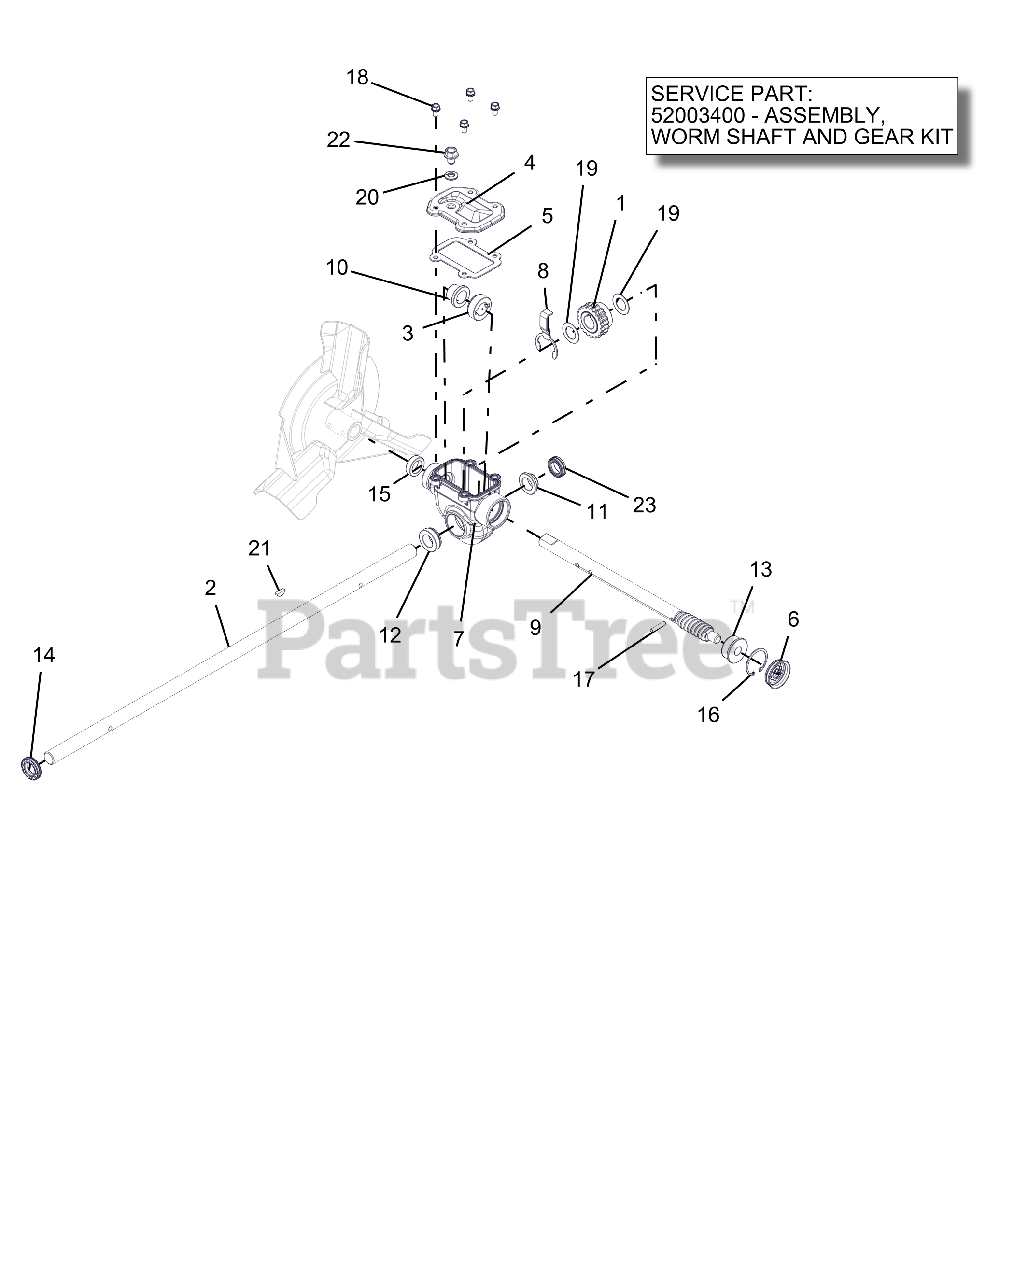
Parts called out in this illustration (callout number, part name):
1	WORM GEAR
2	SHAFT, RAKE-28" (.750 DIA)
3	THRUST COLLAR, .75" ID SLIPFIT
4	COVER, TOP - COMPACT
5	GASKET, TOP - COMPACT GEARCASE
6	COVER, GEAR CASE 1.50"
7	GEARCASE, COMPACT ALUMINUM
8	BUSHING RETAINER, COMPACT
9	SHAFT, WORM - COMPACT
10	BSHG-FLG .755X.878X.75X1.25
11	BSHG-FLG .755X.878X.424X1.25
12	BSHG-FLG COMPACT, RIGHT
13	BSHG-FLG .503X1.303X.62X1.465
14	SEAL-OIL .748X1.300X.250 TBC29
15	SEAL-OIL .748X1.125X.312 TB2-H
16	RG-RTNG-INT 1.500X.050
17	PIN-STR .188X1.00 6150
18	BOLT, SEMS .25-20X.50 GR5 YWZC
19	WSHR-FL-STL .760X1.225X.032 YZ
20	WSHR-BND-SEAL .38X.75X.11 GALV
21	KEY-WDRF .19X.63 HRD #61
22	@SCR-ROLOK .38-16X.50 HWH YWZC
23	SEAL-OIL .748X1.125X.312 TBC29
24	SHAFT AND WORM GEAR ASSEMBLY
